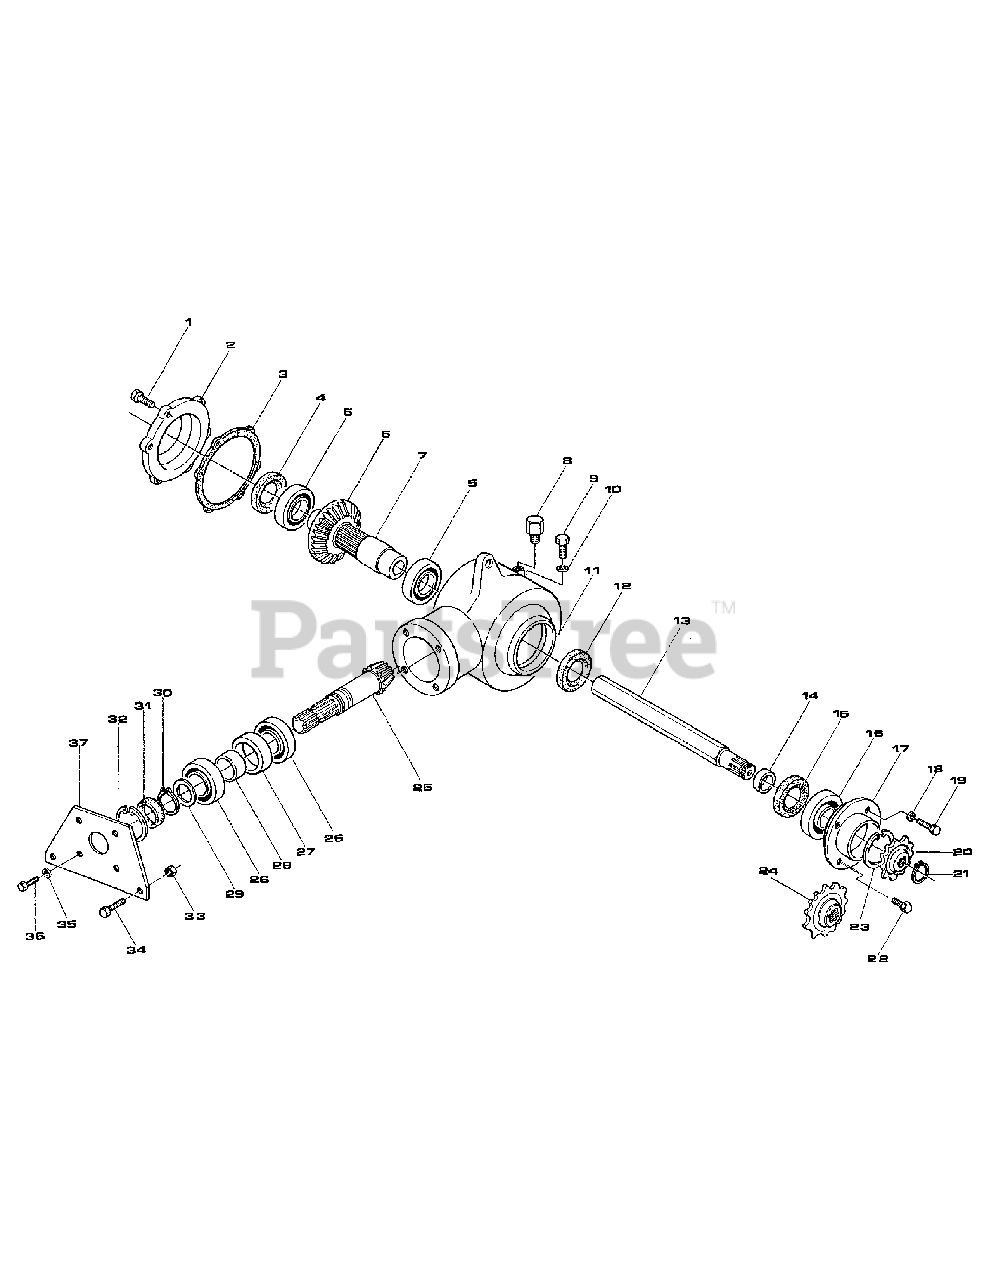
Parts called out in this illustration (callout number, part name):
1	Hex bolt M10x20
2	Gear cover
4	Oil seal 60.75.8
5	Bearing 6212
6	Ring gear
7	Shaft coupling
8	Breather cap
9	Hex bolt M16x50
10	Flat washer Ø16
11	Gearbox housing
12	Oil seal 60.80.10
13	Hexagonal shaft 74"
14	Spacer
15	Oil seal 55.80.10
16	Bearing 6309
17	Top shaft flange
18	Lock washer Ø10
19	Hex bolt M10x40
20	Sprocket Z12
21	Outer snap ring Ø45
22	Hex bolt M10x25
23	Inner snap ring Ø100
24	Sprocket Z14
25	Pinion gear
26	Bearing 6308
27	Spacer
28	Spacer
29	Spacer washer
30	Outer snap ring Ø40
31	Oil seal 40.90.8 BASL
32	Inner snap ring Ø90
33	Nut M14
34	Hex bolt M14x40
35	Flat washer Ø12
36	Hex bolt M12x30
37	Gearbox front cover
